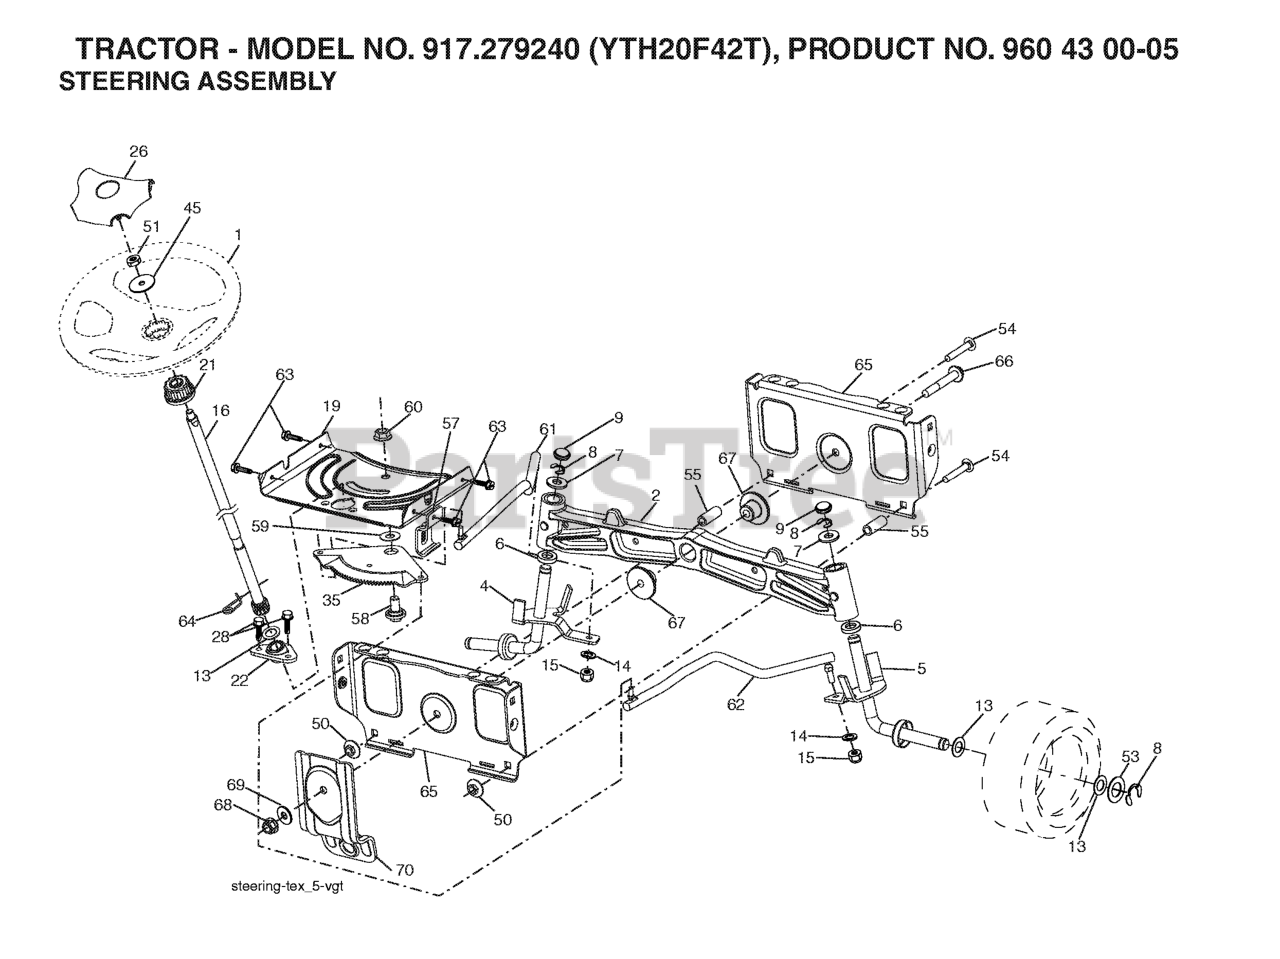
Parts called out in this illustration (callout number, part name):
1	WHEEL.STEERING.LEGEND2.GRY
2	AXLE.CAST.IRON
4	SPINDLE.WELDED.LH.15"TEX
5	SPINDLE.WELDED.RH.15"T
6	THRUST WASHER
9	CAP.SPINDLE.BLACK
14	WASHER, LOCK 3/8
15	NUT CROWNLOCK 3/8-24
16	SHAFT.STEER.STEALTH.DD
19	PLATE.STEER.DDL.NLT/NG
21	ADAPTER, WHEEL STNG..
22	BUSHING.ASM.STEERING.A
26	INSERT.CAP.STRG.WH.GRAY
28	SCREW, 3/8-16X3/4
35	GEAR.SECTOR.PLATE.DDL.
45	WASHER 9/16"ID, 2 3/8"OD
50	NUT LOCK FLG 3/8-16 UNC
51	NUT.HEX.1/2-20
53	WASHER.HARDENED
55	SPACER.BRACE.AXLE (2 2)
57	BRKT.UPSTOP.GT/LT.TEX
58	BOLT.SHOULDER.SECTOR.P
59	WASHER.THURST.SECTOR.S
60	NUT FLANGE LOCK 5/8-11
61	DRAGLINK.LH.BALLSTUD.D
62	DRAGLINK.RH.BALLSTUD.D
63	SCREW
64	RETAINER.CLIP.SPRING.S
65	BRACE.AXLE.FRONT.NLT/N
66	BOLT HEX FGHD 7/16-14 X 3 SERR
67	BUSHING.PM.FRONT AXLE
68	NUT.LOCK.FLANGE.7/16
69	WASHER.1.5X.505X.118
70	BRKT.DECK.SUSPENSION.F
